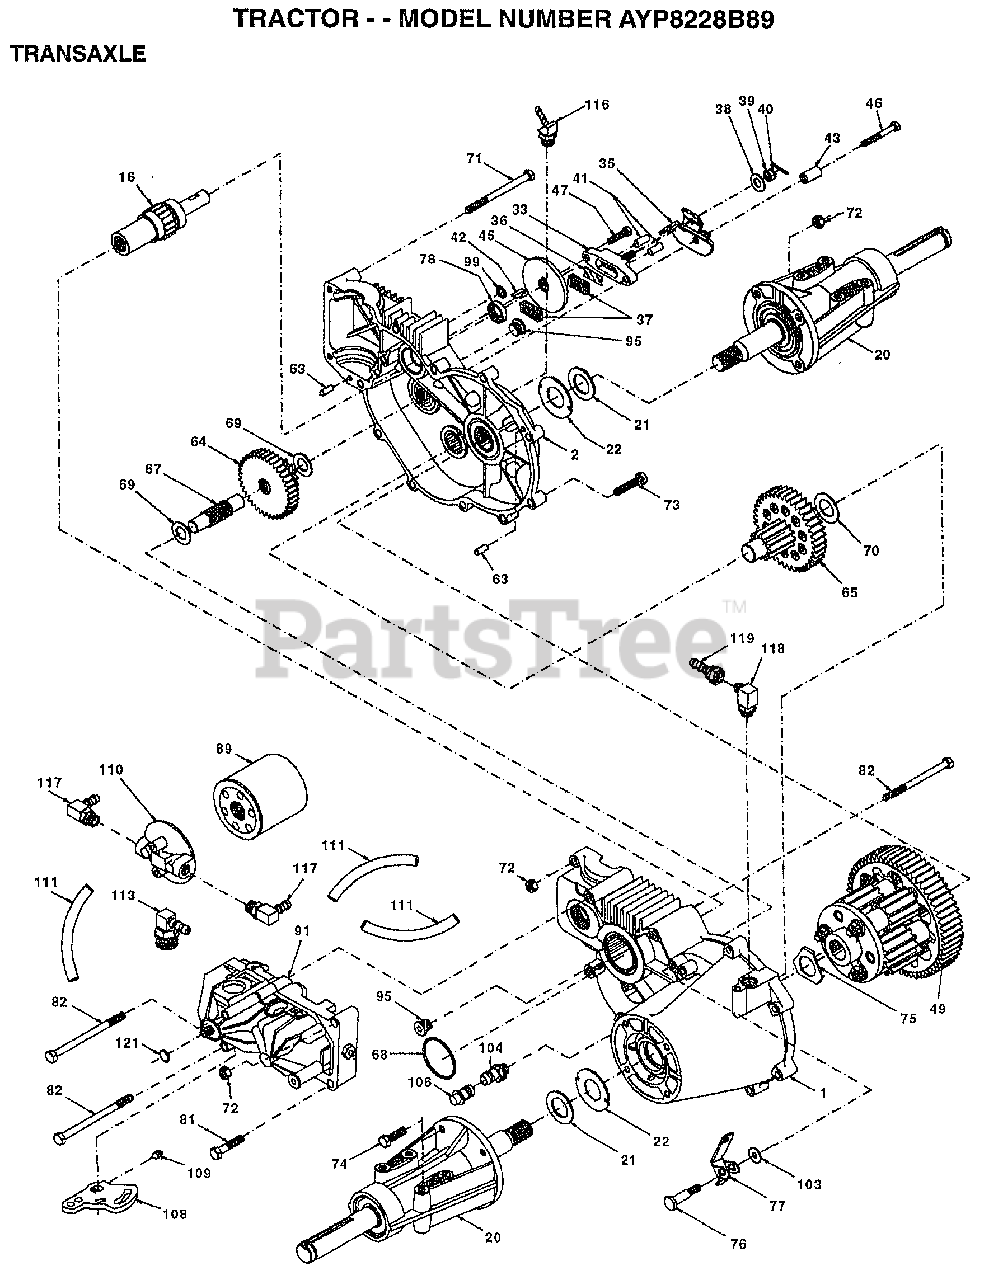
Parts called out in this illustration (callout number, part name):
1	HOUSING LH 70086
2	HOUSING RH 70088
16	SHAFT BRAKE 62877
20	AXLE MTG 70087
21	WASHER 44805
22	WASHER 44806
33	YOKE.BRAKE.62589
35	ARM BRAKE 50214
36	PUCK PLATE 44134
37	PUCK BRAKE 44132
38	WASHER HYD 44130
41	PIN BRAKE 44127
42	KEY HI PRO 44143
43	SPACER 50259
45	DISC BRAKE 44090
46	BOLT 1/4-20 44276
47	BOLT 1/4-20 44433
49	DIFFERENTIAL62834
63	PIN DOWL 44757
64	GEAR R14-38 44775
65	PINION DRIV 70051
67	SHAFT-44779
68	O RING 44781
69	WASHER 44795
70	WASHER 44794
71	BOLT 5/16 44827
72	NUT HXLK 43064
73	BOLT 5/16 44841
74	SCREW 5/16 45089
75	WASHER DIF 44880
76	BOLT SHOULD 44785
77	ARM FREEWHL 44786
78	SEAL.OIL.44761
81	BOLT 5/16 43084
82	BOLT 5/16 44820
89	FILTER SPIN 50037
95	PLUG.9005110-5600
103	WASHER.50169
104	CAP.VENT.70109
106	O-RING.ASM.70110
108	ARM.CONTROL.45007
109	SCREW.SET.50018.
110	FILTER.HEAD.50207
111	HOSE.5/16.50208.
113	FITTING.SAE.50210
116	FITTING.SAE.50213
117	FITTING.SAE.50249
118	FITTING.MAL.50251
119	FITTING.FEM.50250
121	RING.RET.2003016.
